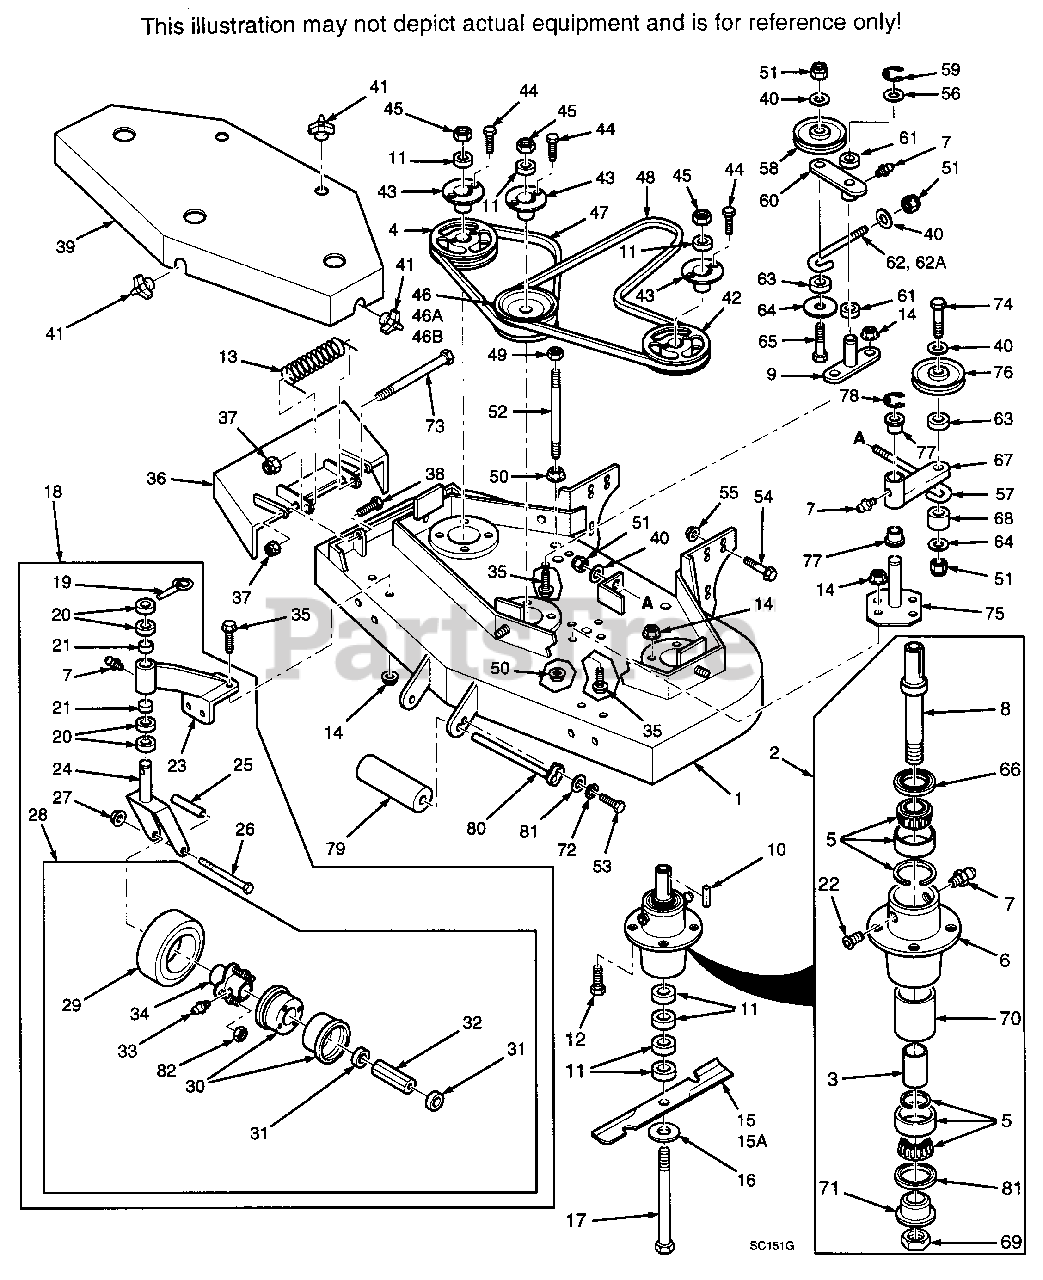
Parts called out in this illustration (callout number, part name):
1	CUTTER DECK(INCLUDES DECALS)
2	SPINDLE ASSEMBLY
3	SLEEVE, CUTTER SPINDLE
4	PULLEY
5	TAPERED BEARING(TWO)
6	SPINDLE HOUSING
7	GREASE FITTING STR. 1/4-28
8	SPINDLE SHAFT
9	IDLER PIVOT
10	KEY, 1/4 X 1/4 X 2"
11	SPACER, CUTTER BLADE
12	HEX HEAD BOLT, 5/16-18 X 1-1/4"
13	SPRING, CHUTE RETURN
14	NUT, 5/16-18 SERR. FLANGE
15	CUTTER BLADE 16-1/2"
15A	CUTTER BLADE 16-1/2" HIGH LIFT
16	FLAT WASHER,(.688 X 1.75 X .134)
17	HEX HEAD BOLT, 5/8-11 X 9-1/2"
18	CASTER ASSY.(INCL. 19-28)
19	QUICK PIN
20	SPACER, CASTER YOKE, 1/2" THICK
21	BUSHING, 5/8 X 1", FLANGED
22	RELIEF FITTING, CUTTER SPINDLE
23	SUPPORT ASSY.,(INCL. 21-23)
24	CASTER YOKE
25	SLEEVE, CASTER WHEEL BEARING
26	HEX HEAD BOLT, 1/2-13 X 5-1/2"
27	NUT, 1/2-13 ELASTIC STOP
28	WHEEL ASSY.,(INCL. 29-34,81)
29	TIRE ONLY, CASTER WHEEL
30	RIM PAIR, CASTER WHEEL
31	BEARING RETAINER, CASTER WHEEL
32	ROLLER BEARING, CASTER WHEEL
33	GREASE FITTING 45 DEG., 1/4-28
34	HUB ASSY.,(INCL. BOLTS)
35	CAPSCREW, 5/16-18 X 3/4"
36A	DISCHARGE CHUTE
37	NUT, 5/16-18 ELASTIC STOP
39	BELT COVER,(INCL. DECALS)
40	FLAT WASHER,(.391 X .938 X .105)
41	WING NUT, 3/8-16
42	PULLEY
43	TAPERED HUB
45	NUT, 5/8-11 HEX HEAD
46	PULLEY, DOUBLE
47	BELT, RH BLADE DRIVE
48	BELT, BLADE DRIVE
49	NUT, 3/8-16 CENTERLOCK
50	NUT, 3/8-16 SERR. FLANGE
51	NUT, 3/8-16 ELASTIC STOP
52	SUPPORT, BELT COVER
53	HEX HEAD BOLT, 5/16-18 X 3/4"
54	CAPSCREW, 7/16-14 X 1" SERR.
55	NUT, 7/16-14 SERR. FLANGE
56	FLAT WASHER, 3/4 SPECIAL
57	J-HOOK
58	IDLER PULLEY, "V" GROOVE
59	RETAINING RING, 3/4" EXT. "E"
60	IDLER ARM ASSY.(INCL. 22 & 61)
61	BUSHING, 3/4 X 1/2
62	J-HOOK, IDLER PULLEY
63	SPACER, PULLEY
64	FLAT WASHER, 3/8 X 1-1/2 X 16 GA.
66	SEAL, CUTTER SPINDLE
67	IDLER ARM ASSY.,(INCL. 22 & 77)
68	SPACER, J-HOOK
69	NUT, CUTTER SPINDLE
70	SPACER, OUTSIDE
71	SPINDLE BUSHING
75	IDLER PIVOT
76	IDLER PULLEY, CLUTCH BELT
77	BUSHING, 1-1/8 X 1.0 FLANGED
78	RETAINING RING, 1-1/8 EXT. "E"
81	SEAL, CUTTER SPINDLE
82	NUT, 5/16-24 TAPERED
NS	INNER TUBE ONLY, CASTER WHEEL
